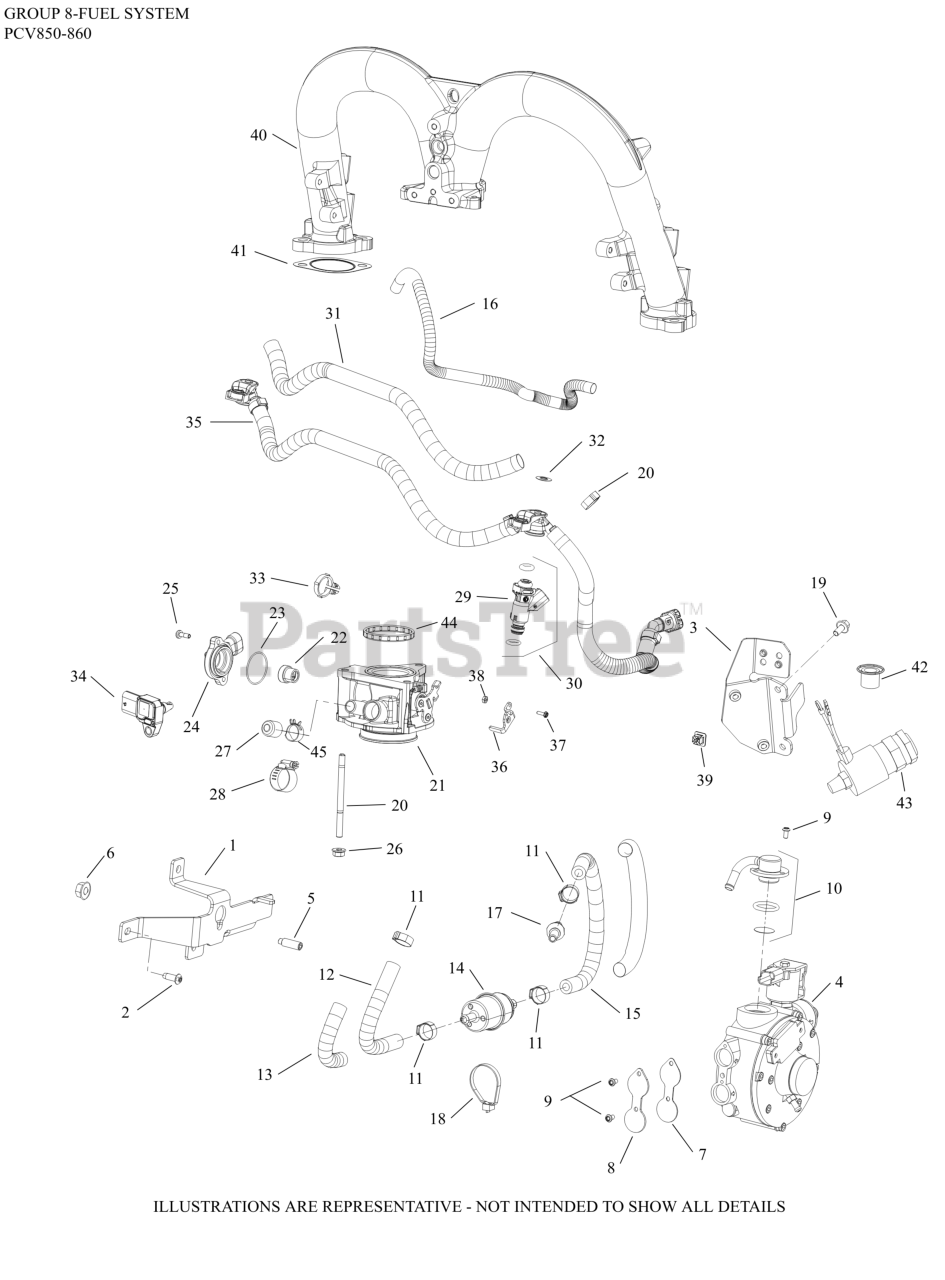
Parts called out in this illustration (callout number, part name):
1	BRACKET, LP REGULATOR
2	SCREW, THREAD FORMING
3	BRACKET, PULSE PUMP
4	REGULATOR, W/RTV
5	STUD, LP REGULATOR
6	NUT, FLG M8X1.25
8	COVER, OIL PORT
9	SCREW, STARTER SWITCH
10	KIT, OUTLET FITTING W/O-RING LPG
11	CLAMP, HOSE
12	HOSE, FUEL LOW PROPANE
13	SLEEVE, ANTI ABRASION-USE 25 431 12-S
14	PROPANE FUEL FILTER-(#2505050S)
15	HOSE, FUEL LOW PERMEATION
16	SLEEVE, ANTI-ABRASION
17	FITTING, FUEL - STRAIGHT
19	SCREW, FLG M6X1.0X12
20	STUD,M6X1.0X84
21	BODY, THROTTLE ASM (30)
22	MAGNET ASSEMBLY, TPS
23	O-RING, TPS SENSOR
24	SENSOR, THROTTLE POSITION
25	NUT, FLG M6X1.0
27	CAP, MASKING
29	INJECTOR, GASEOUS FUEL
30	KIT, FUEL INJECTOR O-RING
31	SLEEVE, ANTI ABRASION
32	CLIP, RETAINER
33	CLIP, SNAP-IN-USE 25 018 05-S
34	SENSOR, T-MAP
35	FUEL HOSE ASSY(ECV,FCV,EZT,EKT,PCH,PCV)
41	MANIFOLD, INTAKE EFI
44	O-RING, THROTTLE BODY
NI	RETAINER, WIRE HARNESS
NI	KIT, LOCK-OFF ASSY LPG (A7-175)
NI	KIT, VAPORIZER FILTER REPL'MT LPG(A7-170
NI	KIT, PLUG W/O-RING LPG (A7-173)
